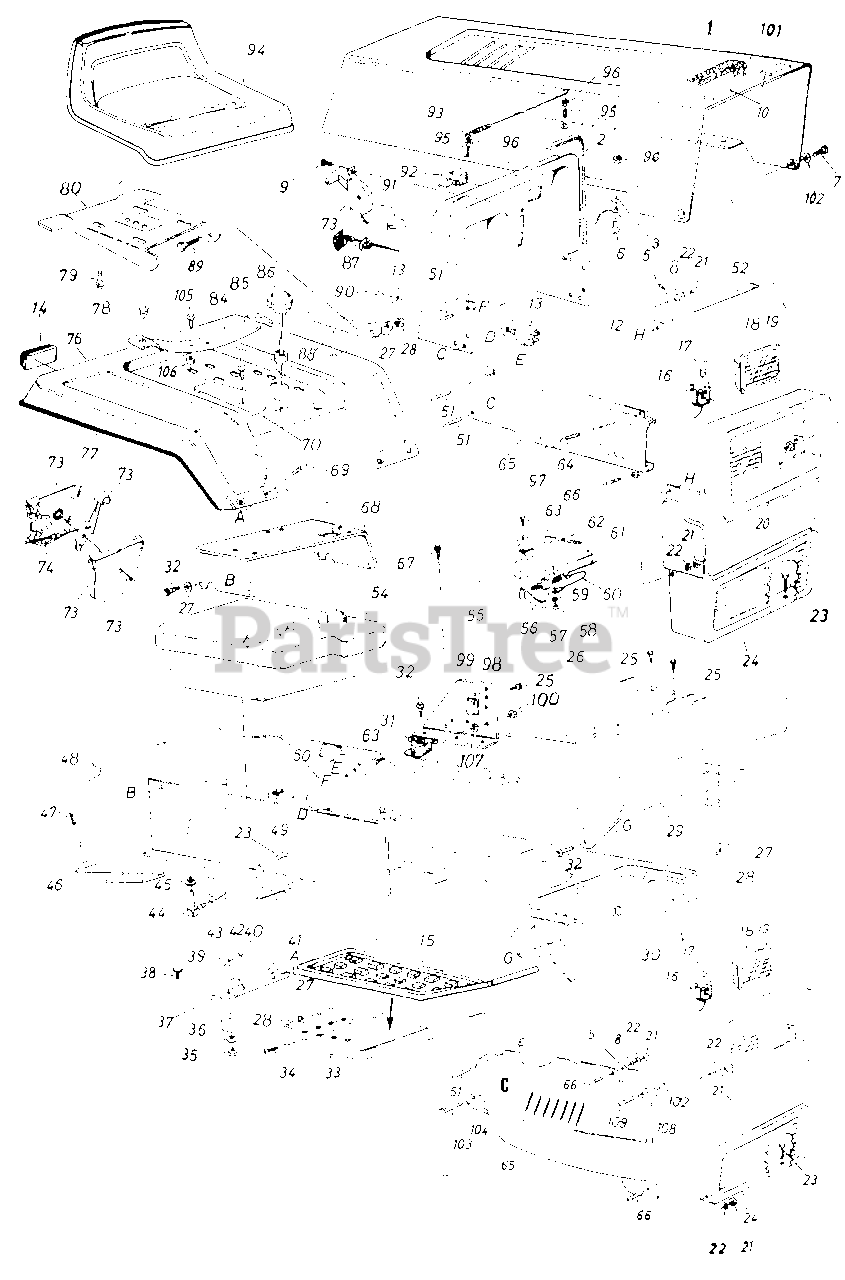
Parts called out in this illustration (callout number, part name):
1	Hood
2	Trim Strip-31" Lg.
3	Fl-Wash. .20" I.D. x .41 "
5	Hood Stop
6	Truss Hd. Mach. Scr. #10-24 x 1.0" Lg.*
7	Shld. Bolt .375 Dia. x .125
8	Fl-Wash. 1/4" I.D.
9	Truss Mach. AB-Tap Scr. #10 x .50" Lg.
10	Foam Strip
12	Dash Ass'y.
13	Ignition Switch
14	Reflector
15	Foot Pad
16	Socket
17	Lamp
18	Headlight Housing
19	Lens
20	L-Nut 1/4-28 Thd.
21	Hex Nut 1/4-20 Thd.
22	L-Wash. 1/4" I.D.*
23	Hex Bolt 5/16-18 x .75" Lg.
24	Grille
25	Hex Wash. Hd. Scr. 1/4" x .50" Lg.
26	Battery Plate
27	L-Wash. 5/16" I.D.
28	Hex Nut 5/16-18 Thd.
29	Grille Mounting Bracket
30	Lower Frame Ass'y.
31	Solenoid
32	Hex Thd. Rolling Scr. 5/16-24 x .75" Lg.
33	Running Board-R.H.
34	Truss Mach. Scr. 5/16-18 x .75 Lg.
35	Hex Nut 5/16-18 Thd.*
36	Bell-Wash. .34" I.D. x .87"
39	Hex Nut 1/4-20 Thd.*
40	L-Wash. 1/4" I.D.
41	Running Board Rod
42	Fuel Line 40" Lg.
43	Hose Clamp 3/8"
44	90ø Nipple
45	Bushing
46	Hitch Rod
47	Internal Cotterpin
48	Hitch Plate
49	Speed Nut
50	Dash Support Brkt.-R.H.
51	Hex Wash. Hd. Tap Scr. 1/4 x .75" Lg.
52	Tie Strap
54	Fuel Tank
55	Transmission Cover Ass'y.
56	Switch Actuator Lever
57	Safety Switch
58	Hex Nut 1/4-20 Thd.
59	L-Wash. 1/4" I.D.*
60	Electric Wire
61	Reverse Lockout Wire Harness
62	Snap Bushing
63	Hex Bolt 1/4-20 x .50" Lg.
64	Truss Hd. Scr. 1/4-20 x .75"
66	Truss Mach. Scr. 1/4-20 x .50" Lg.
67	Truss Mach. "B" Tap Scr. #10 x .50" Lg.
68	Seat Mounting Channel
69	Carriage Bolt 1/4-20 x .50"
70	Seat Bracket-R.H.
73	Throttle Control Box Ass'y.
74	Throttle Control Wire
78	Grommet
79	Hex Wash. Hd. AB-Tap Scr. 318 x .75" Lg.
80	Seat Pivot Bracket
84	Seat Spring
85	Hex Wash. Hd. Self-Tap Scr. 5/16-18 x .50" Lg.
86	Gas Cap w/Gauge
87	Choke Control Comp.
88	Seat Bracket-L.H.
89	Shld. Bolt .437" Dia. x .162"
90	Ignition Key
91	Light Switch
92	Ammeter
93	Hood Spring
94	Seat Ass'y.
95	Hex Bolt #10-24 x 1.0" Lg.
96	Hex Sems Nut #10 x .24 Thd.
97	Rubber Strip 1/2" Sq. X 21/2"
98	Circuit Breaker
99	Dash Support Brkt.L.H.
100	Hex Sems Nut 1/4-20 Thd.
101	PVC Foam Strip
102	Washer .34" I.D. x .62" O.D.
103	Hex HD. Tap Scr. 1/4-20 x 1.75" Lg.
104	Spacer.255" I.D.
105	Hex Tap Scr. 5/16-18 x 1.25" Lg.
106	Spacer.38" I.D.
107	Ext. L-Wash. .44" I.D.
108	Shld. Spacer .125" Lg.
109	Truss HD. Scr. 1/4-20 x 1.0"Lg.
